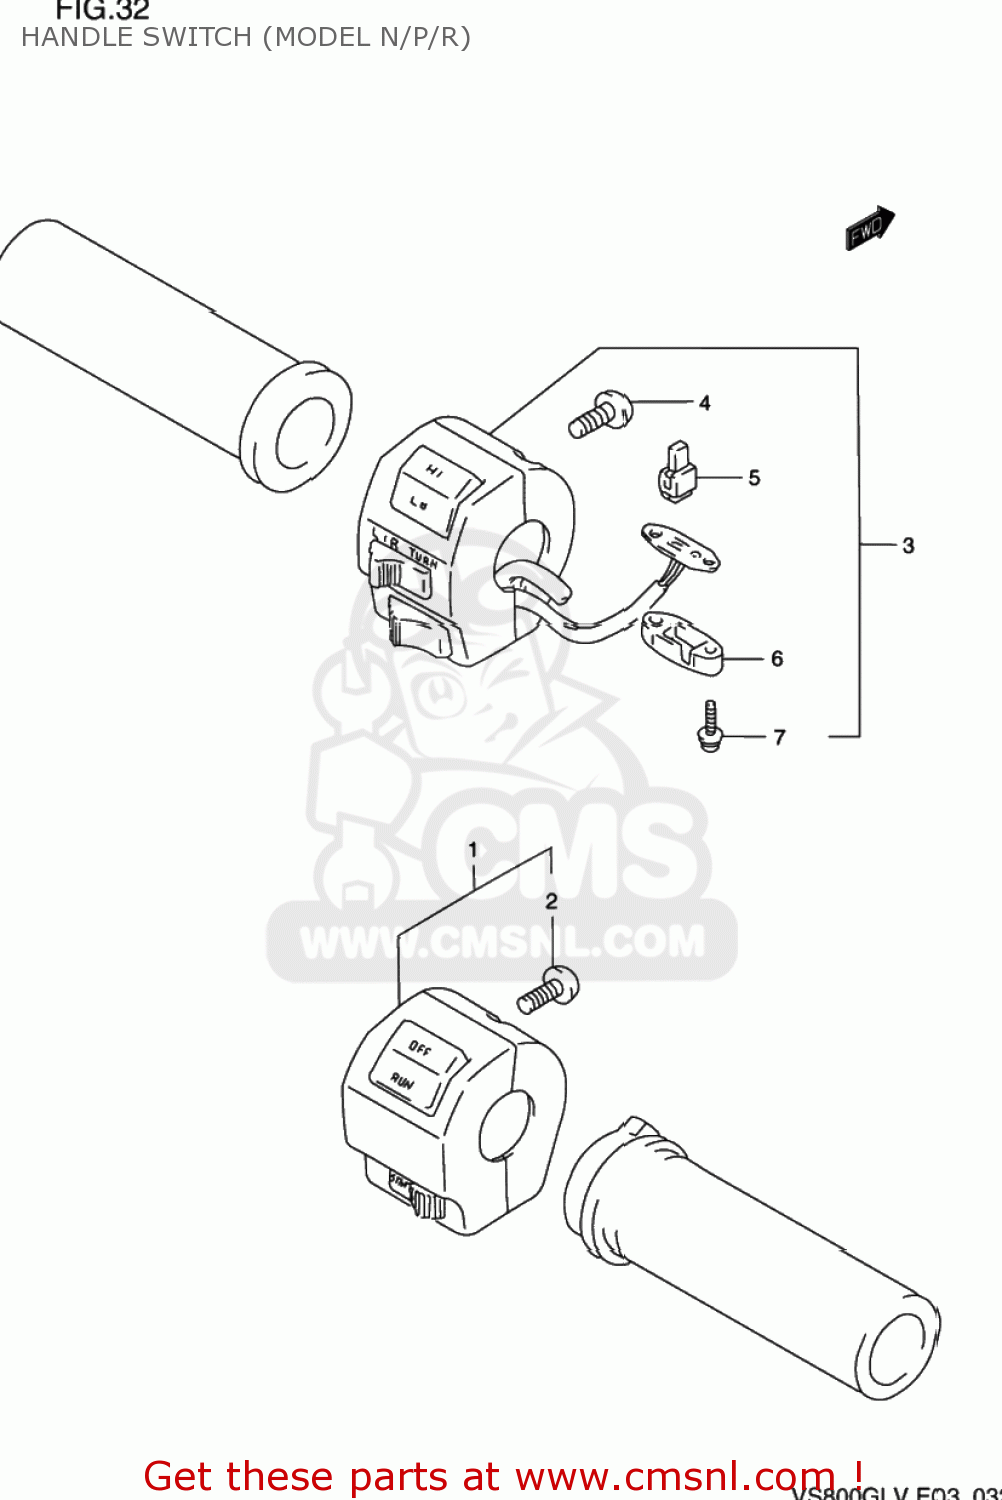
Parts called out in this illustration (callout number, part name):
1	SWITCH ASSY,HANDLE,R
2	SCREW
3	SWITCH ASSY,HANDLE,L
4	SCREW
5	CONTACT,SWITCH
6	COVER,CLUTCH SWITCH
7	SCREW
